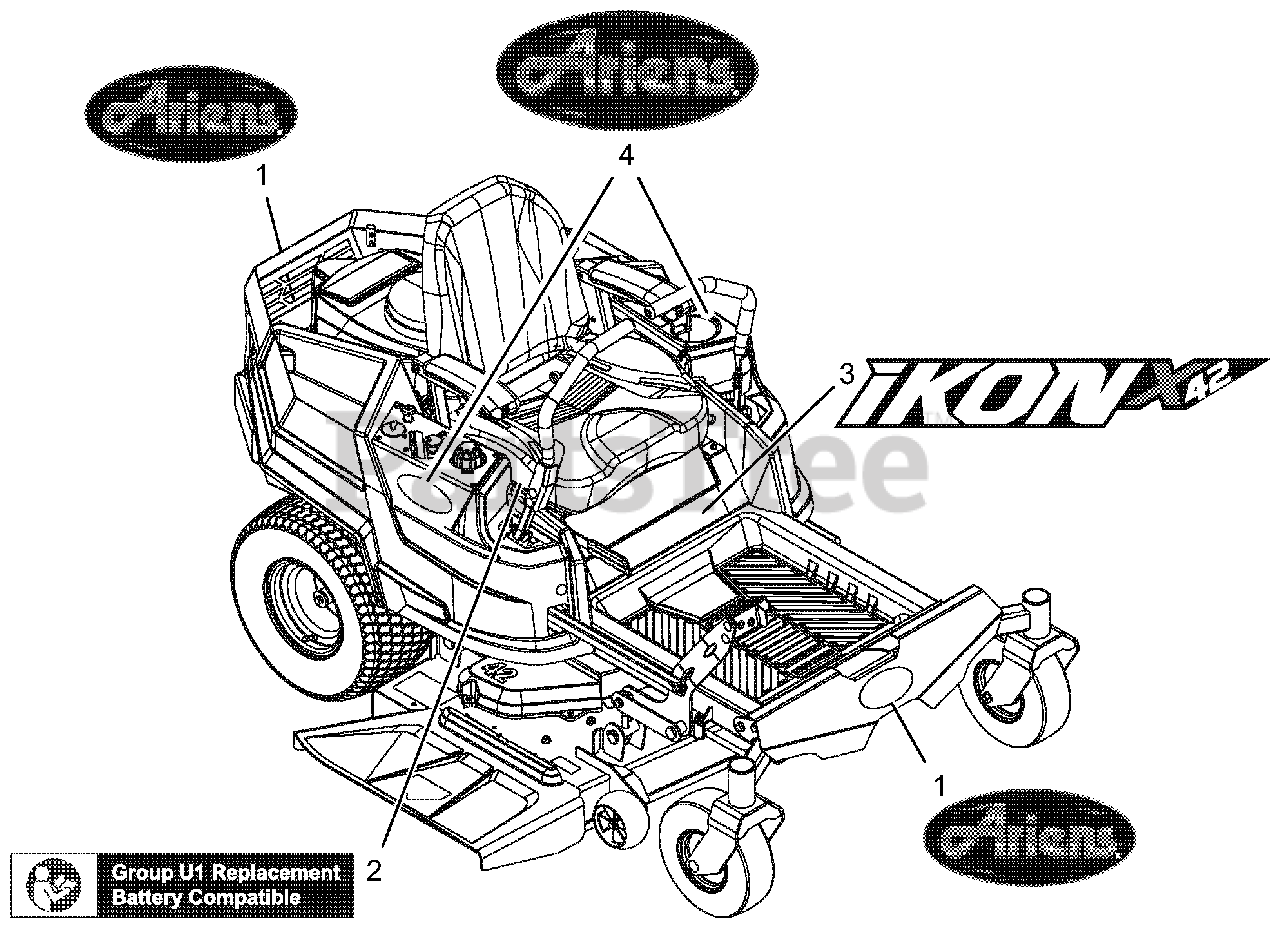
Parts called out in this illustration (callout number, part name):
1	DECAL, ARIENS JEWEL
2	DECAL, U1 BATTERY REPLACEMENT
3	DECAL, ARIENS IKON 42
4	DECAL, ARIENS JEWEL (LARGE)
